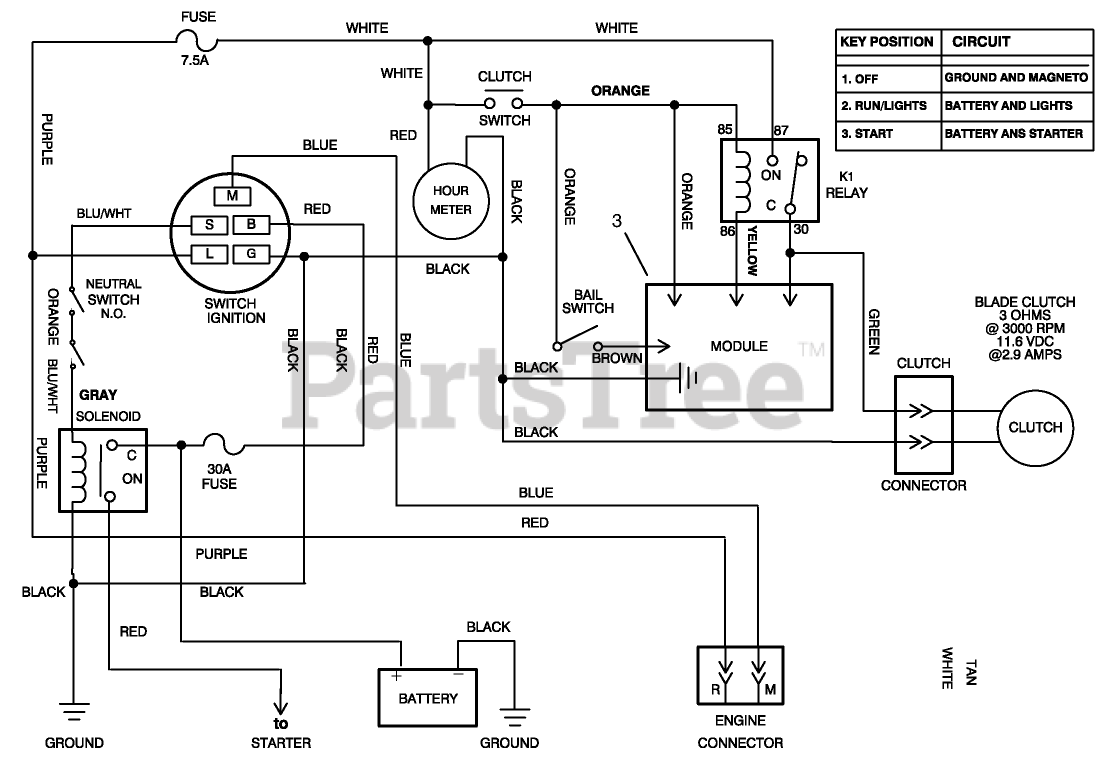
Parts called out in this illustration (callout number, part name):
1	HARNESS - WIRE
2	RELAY
3	MODULE
